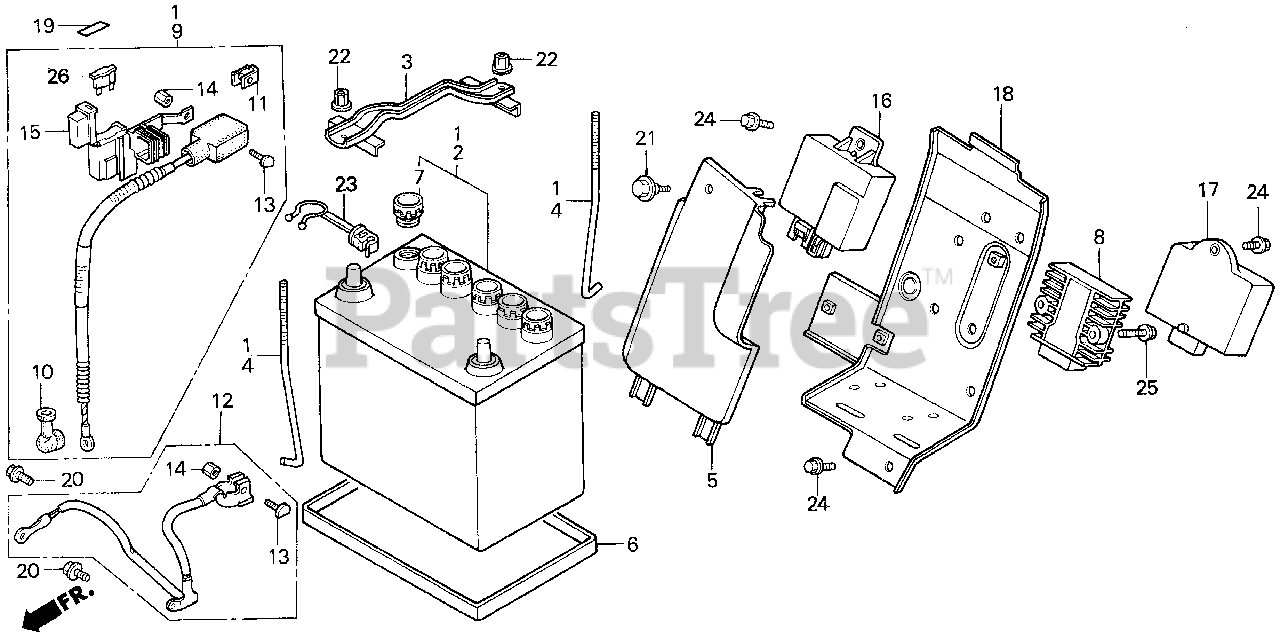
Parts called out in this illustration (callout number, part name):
1	BATTERY KIT (N/A: SEE COMPONENTS)
2	BATTERY ASSY. (32A19RT-S) (YUASA)
3	PLATE, BATTERY SETTING
4	BOLT, BATTERY SETTING (185MM)
4	BOLT, BATTERY SETTING (210MM)
5	COVER, ELECTRIC PARTS
6	TRAY, BATTERY
7	PLUG, VENT (YUASA)
8	RECTIFIER ASSY., REGULATOR
9	CABLE ASSY., STARTER
10	COVER, STARTER MOTOR TERMINAL
11	STOPPER, MAIN FUSE
12	CABLE ASSY., GROUND
13	BOLT, BATTERY TERMINAL (SUMITOMO)
13	BOLT, BATTERY TERMINAL
14	NUT, BATTERY TERMINAL (SUMITOMO)
15	CASE, MAIN FUSE
17	UNIT, FUEL CONTROL
18	BRACKET, ELECTRIC PARTS
19	MARK, MAIN FUSE (ENGLISH)
20	BOLT, FLANGE (6X12) (CT200)
21	BOLT, BUMPER
22	NUT, HEX. (6MM)
23	CLAMP, WIRE HARNESS
24	BOLT, FLANGE (6X12)
25	BOLT, FLANGE (6X20)
26	FUSE, BLADE (20A)
